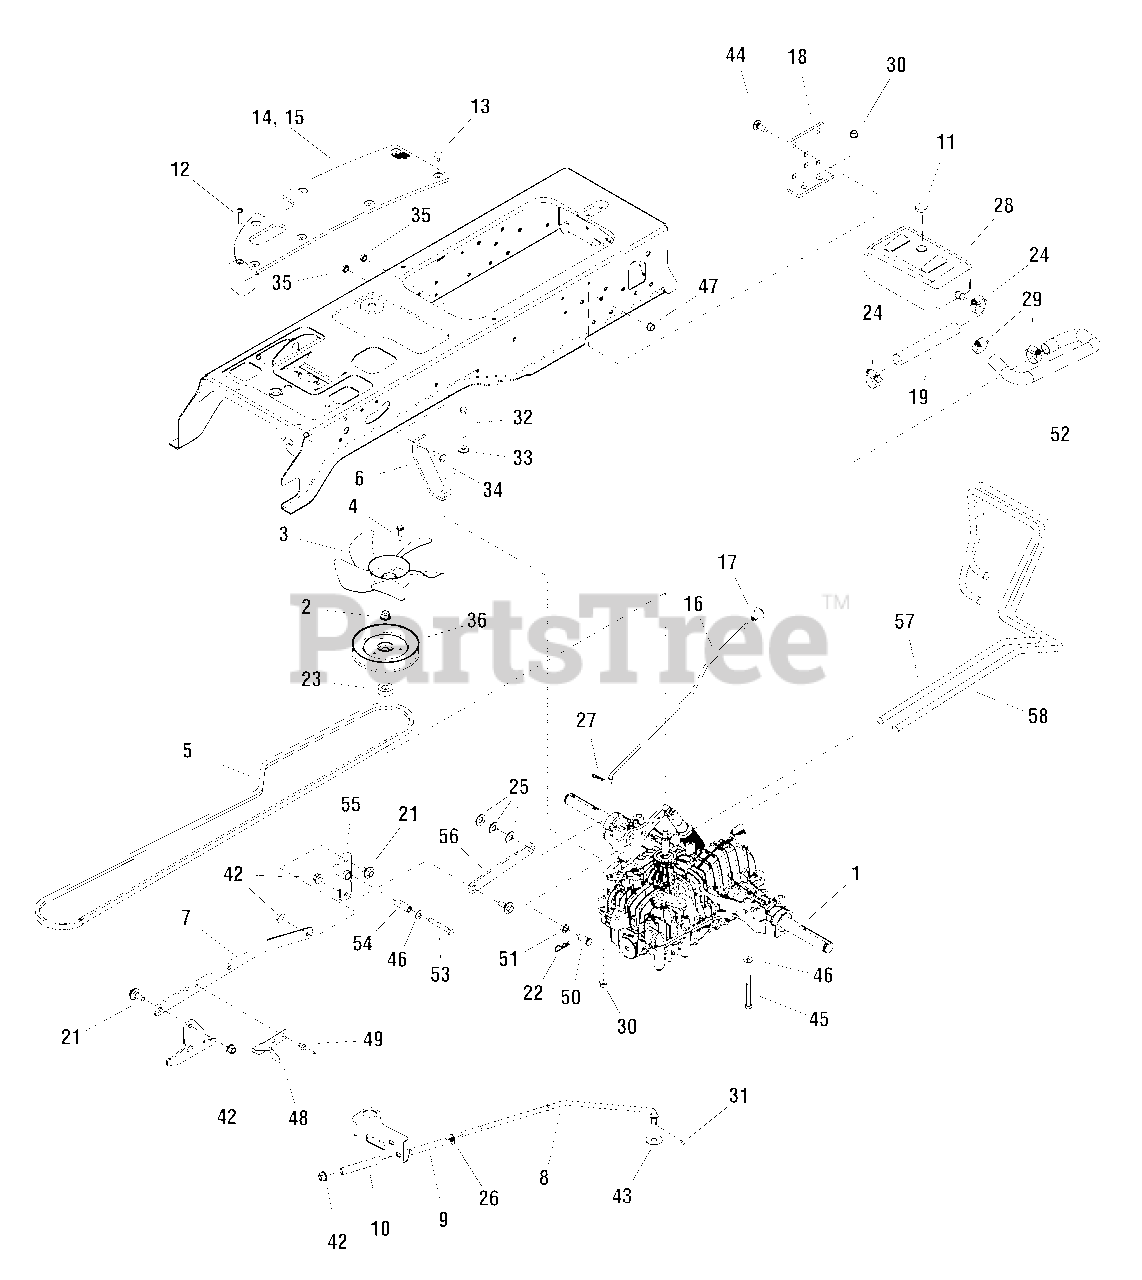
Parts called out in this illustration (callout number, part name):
1	TRANSMISSION ASSEMBLY, K664C
2	NUT, Hex Flange
4	CAPSCREW, Hex Washer Head, Taptite, 1/4-20 x 1-1/4
5	BELT, 94.05
6	STRAP, 4-1/4 Long
7	ARM, Control 7GA
8	ROD, 17-27/64 Long
9	SPRING, Compression
10	SPRING, Compression
11	CAP, Expansion
12	SCREW, Pan Head Torx, 1/4-20 x 1-1/4 Taptite
13	FASTENER, Panel
14	PAD, Footrest L.H.
15	PAD, Footrest R.H.
16	ROD, Free Wheel
17	KNOB, Interior Thread
18	SUPPORT, Transmission
19	HOSE, Hydraulic
21	BOLT, Shoulder, 3/8-16
22	CLIP, Hair Pin
24	CLAMP, Hose Worm
25	WASHER, 1/2
26	WASHER, 3/8
27	PIN, Quick
28	TANK, Oil Natural
29	CLAMP, Hose Worm
30	NUT, Hex Flange 5/16-18 ESNA
31	COTTER PIN
32	CAPSCREW, Hex Head 5/16-18 x 2-1/2 G5
33	WASHER, 5/16
34	BOLT, Carriage, 5/16-18 x 1 G5
35	NUT, Hex KEPS 5/16-18
36	PULLEY & HUB ASSEMBLY
42	NUT, Hex Flange 3/8-16 ESNA
43	WASHER, 7/16
44	BOLT, Carriage 3/8-16 x 1 G5
45	CAPSCREW, Hex Head 5/16-18 x 3 G5
46	WASHER, 5/16
47	NUT, Hex Keps 3/8-16
48	ACTUATOR, Switch
50	PIN, Clevis
52	HOSE, Hydraulic
53	CAPSCREW, Hex Head, 5/16-18 x 2-1/4 G5
55	PIVOT ASSEMBLY, Control
56	ARM, Control
57	TUBE, Hydraulic 4WD
58	TUBE, Hydraulic Rear
65	WASHER, Flat, 3/8
66	CAPSCREW, Hex Head, 5/16-18 x 1
